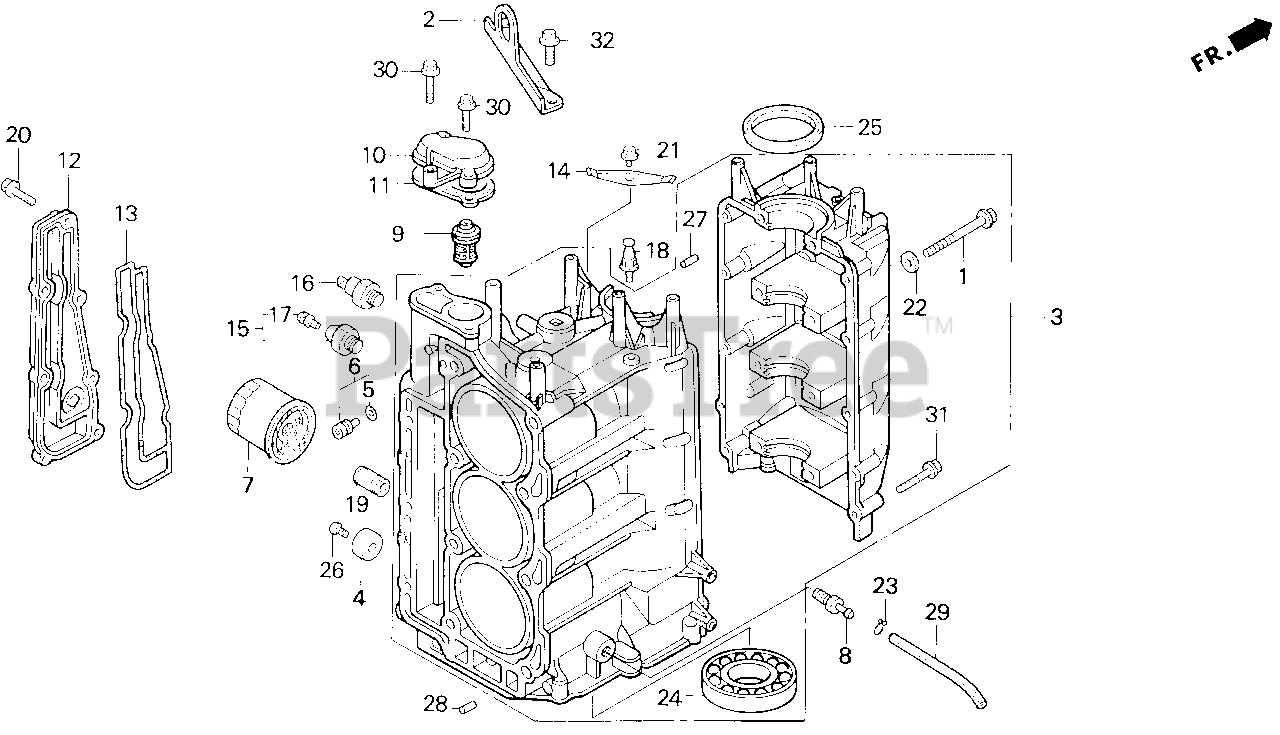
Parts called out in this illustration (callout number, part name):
1	BOLT, FLANGE (8X95)
2	HANGER, ENGINE
3	BLOCK ASSY., CYLINDER *NH8* (DARK GRAY)
4	METAL, ANODE
5	O-RING (4.8X1.9)
6	ORIFICE ASSY., OIL PASSAGE
7	FILTER, OIL (DENSO)
8	JOINT, WATER HOSE
9	THERMOSTAT ASSY. (72 DEGREES C)
10	COVER, THERMOSTAT *NH8* (DARK GRAY)
11	GASKET, THERMOSTAT COVER
12	COVER, WATER JACKET *NH8* (DARK GRAY)
13	GASKET, WATER JACKET COVER
14	HOLDER, WIRE (A)
15	SWITCH, OIL PRESSURE
16	SWITCH ASSY., THERMOSTAT
17	SCREW-WASHER (4X8)
18	BOLT, TIMING BELT ADJUST SPRING
19	HOLDER, OIL FILTER
20	BOLT, FLANGE (6X22)
21	BOLT, FLANGE (6X12)
22	WASHER, PLAIN (8MM)
23	CLIP, TUBE (B8)
24	BEARING, RADIAL BALL (6005)
25	OIL SEAL (56X70X8)
26	SCREW, PAN (6X18)
27	PIN, DOWEL (10X12)
28	PIN A, DOWEL (12X16)
29	BULK HOSE, VACUUM (4.5X1000) (4.5X125)
30	BOLT, FLANGE (6X20)
31	BOLT, FLANGE (6X40)
32	BOLT, FLANGE (8X18)
